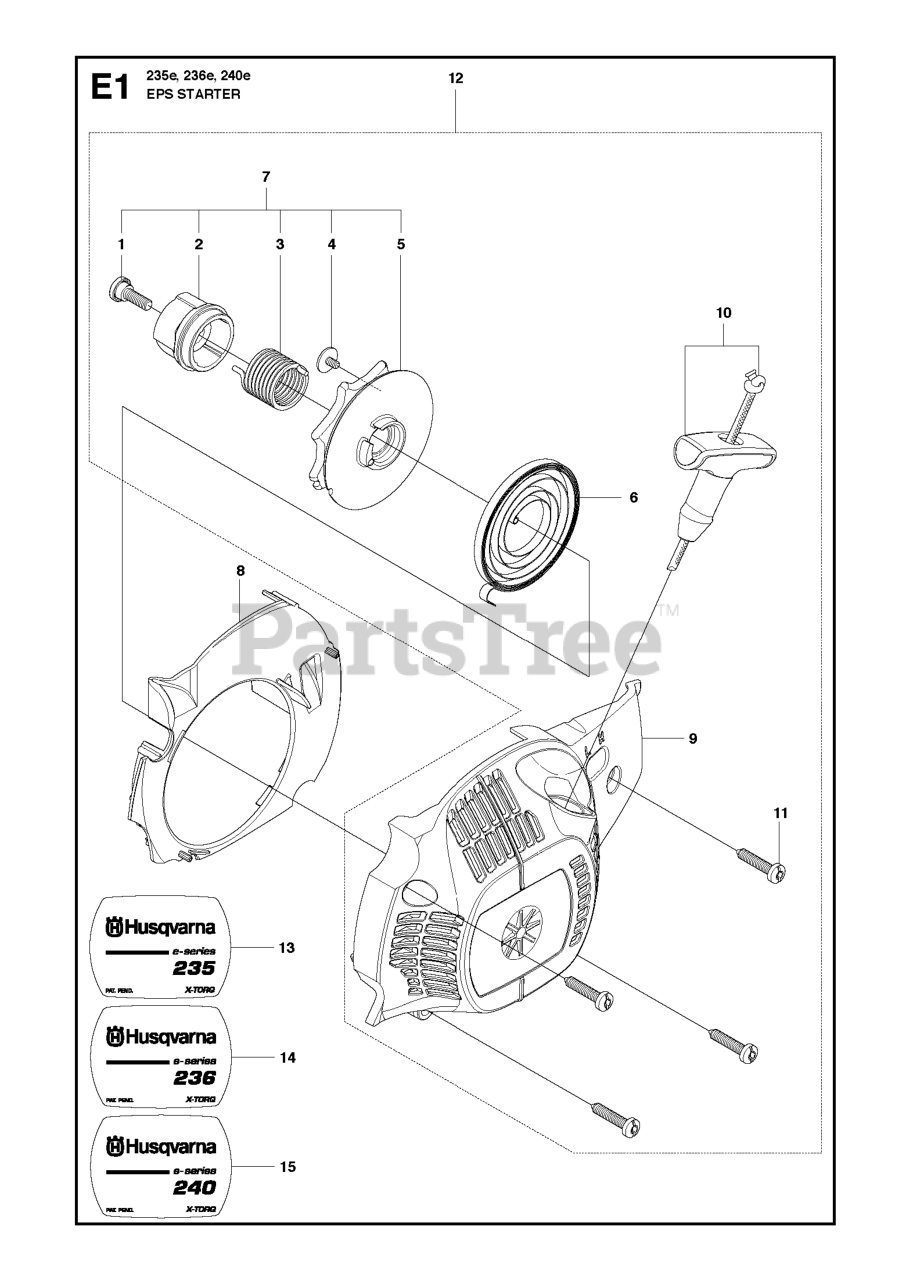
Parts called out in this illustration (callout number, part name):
1	SCREW SHOULDER
2	HUB STARTER EPS
3	SPRING EPS
5	STARTER PULLEY
6	SPRING STARTER
7	KIT EPS STARTER
9	FAN HOUSING
10	STARTER ROPE W/HANDLE
11	SCREW M5.38-14X22.225MM
12	KIT COMPLETE EPS
13	DECAL 235E
15	DECAL 240E
